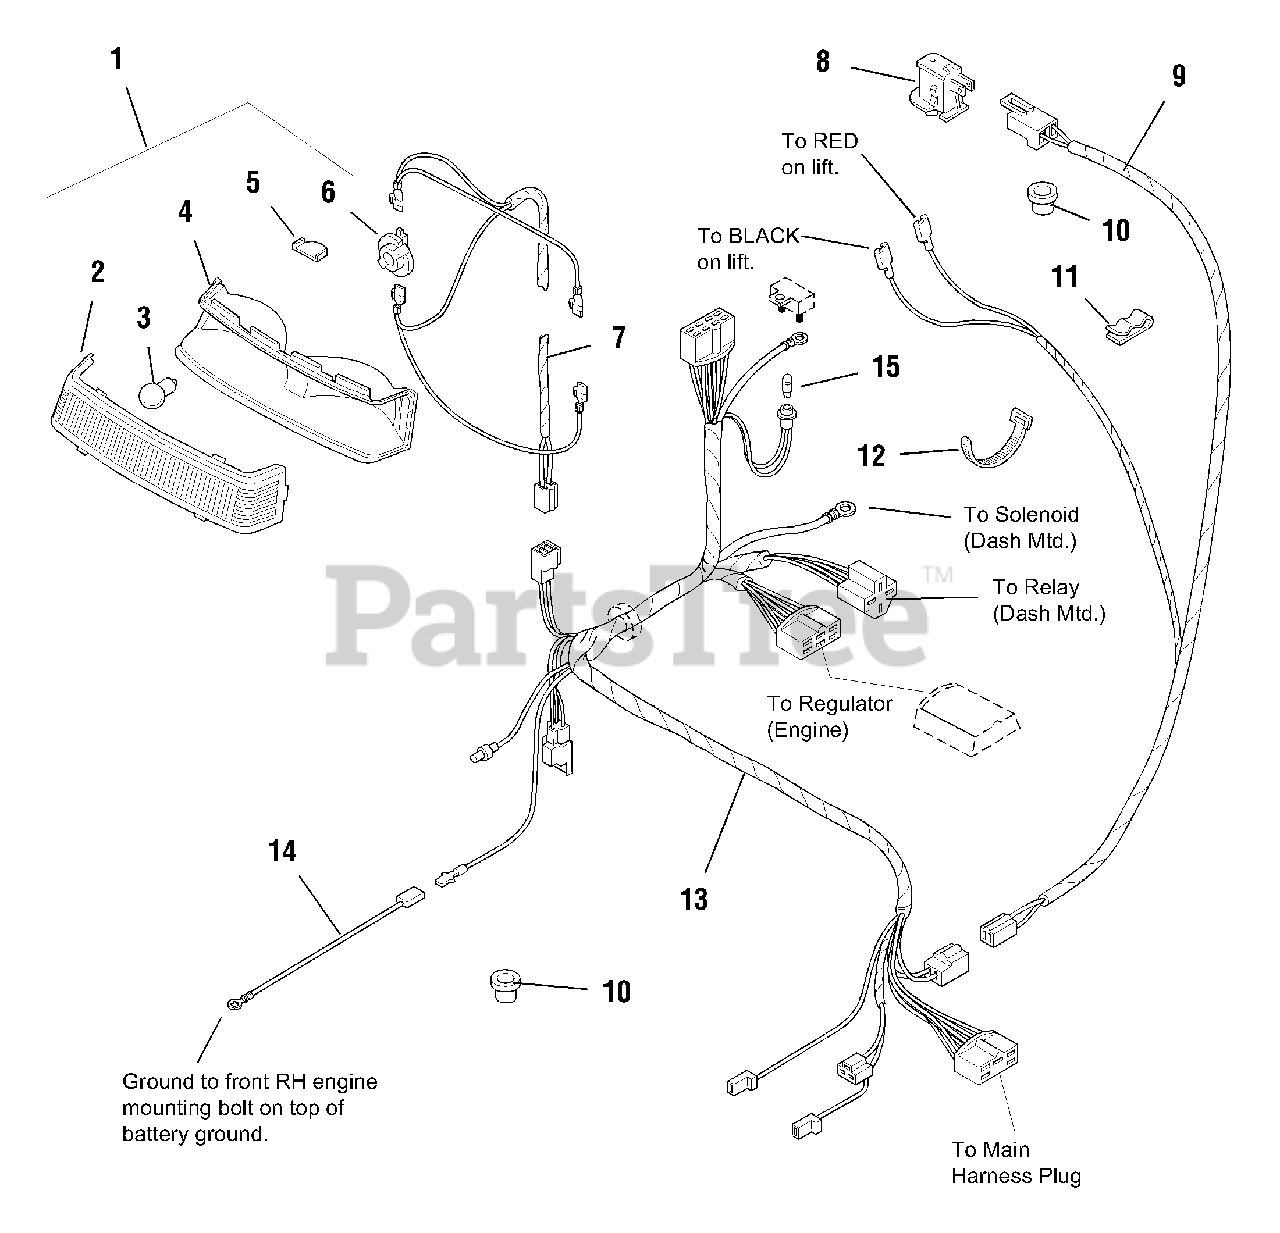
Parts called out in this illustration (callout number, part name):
1	HEADLIGHT ASSY.
2	LENS, Headlight
3	BULB, Headlight, 12.8V
4	BEZEL, Headlight
5	HEAT SHIELD
6	SOCKET, Bulb
7	WIRE ASSY., Headlight
8	SWITCH, Seat, Operator Present
9	WIRE ASSY., Seat Switch and Lift
10	BUSHING, Snap, Small
11	CLIP, Speed
13	HARNESS ASSY., Lower
14	WIRE ASSY., Engine Ground
15	BULB, Indicator, Flashing
